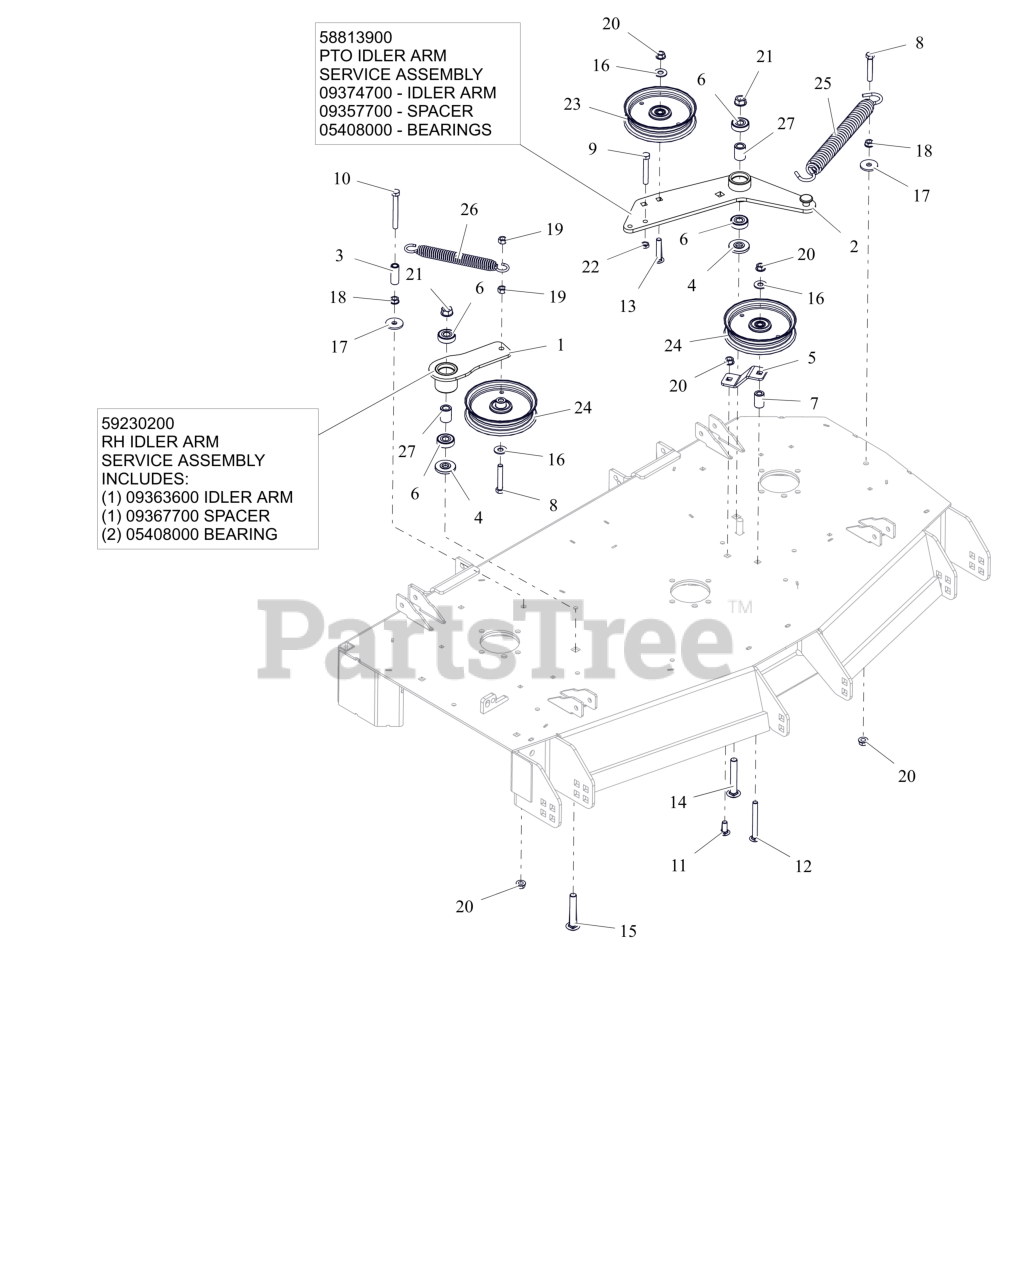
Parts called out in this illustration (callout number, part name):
1	WLDMT, DECK RH IDLER ARM
1	RH IDLER ARM
1	SPACER .510 X .867 X 1.1485
1	BRG-BALL .500X1.38X.437
2	WLDMT, IDLER ARM PT660
2	PTO IDLER ARM
2	SPACER .510 X .867 X 1.1485
2	BRG-BALL .500X1.38X.437
3	SPACER, .375IDX.625ODX1.66 PM
4	SPACER, IDLER ARM
5	PTO FIXED IDLER MTG BRKT -RED
6	BRG-BALL .500X1.38X.437
7	BUSHING, SLV .380X.750X1.190
8	BLT,HEX .38-16X2.25 G5 ZCC
9	BLT, HEX .38-16X2.50 G5 ZCC
10	BLT, HEX .38-16X3.25 G5 ZCC
11	BLT,RHSSN .38-16X1.00 G5 ZCC
12	BLT,RHSSN .38-16X3.50 G5 ZCC
13	BLT,RHSSN.375-16X2.00 G5 ZCC
14	BTL,RHSSN .500-13 X 3.25 G5 ZCC
15	BTL,RHSSN .500-13 X 3 G5 ZCC
16	WSHR,FLT .438X1.00X.083 ZCC
17	WSHR,FLT .406X1.375X.135 ZCC
18	NUT, SPNLK-FLG .38-16 G5 ZCC
19	NUT-LK-CTR .38-16 ZC120
20	NUT-LK-CTR-FLG .375-16 GF ZCC
21	NUT-LK-CTR-FLG .500-13 GG ZCC
22	NUT-JAM .375-16 G2 ZCC
23	PULLEY, FLAT IDLER .500 X .375 W/BRG
24	IDLER- FLAT - 5.00" X .75"
25	SPRING, EXTENSION
26	SPRING- EXTENSION
27	SPACER .510 X .867 X 1.1485
